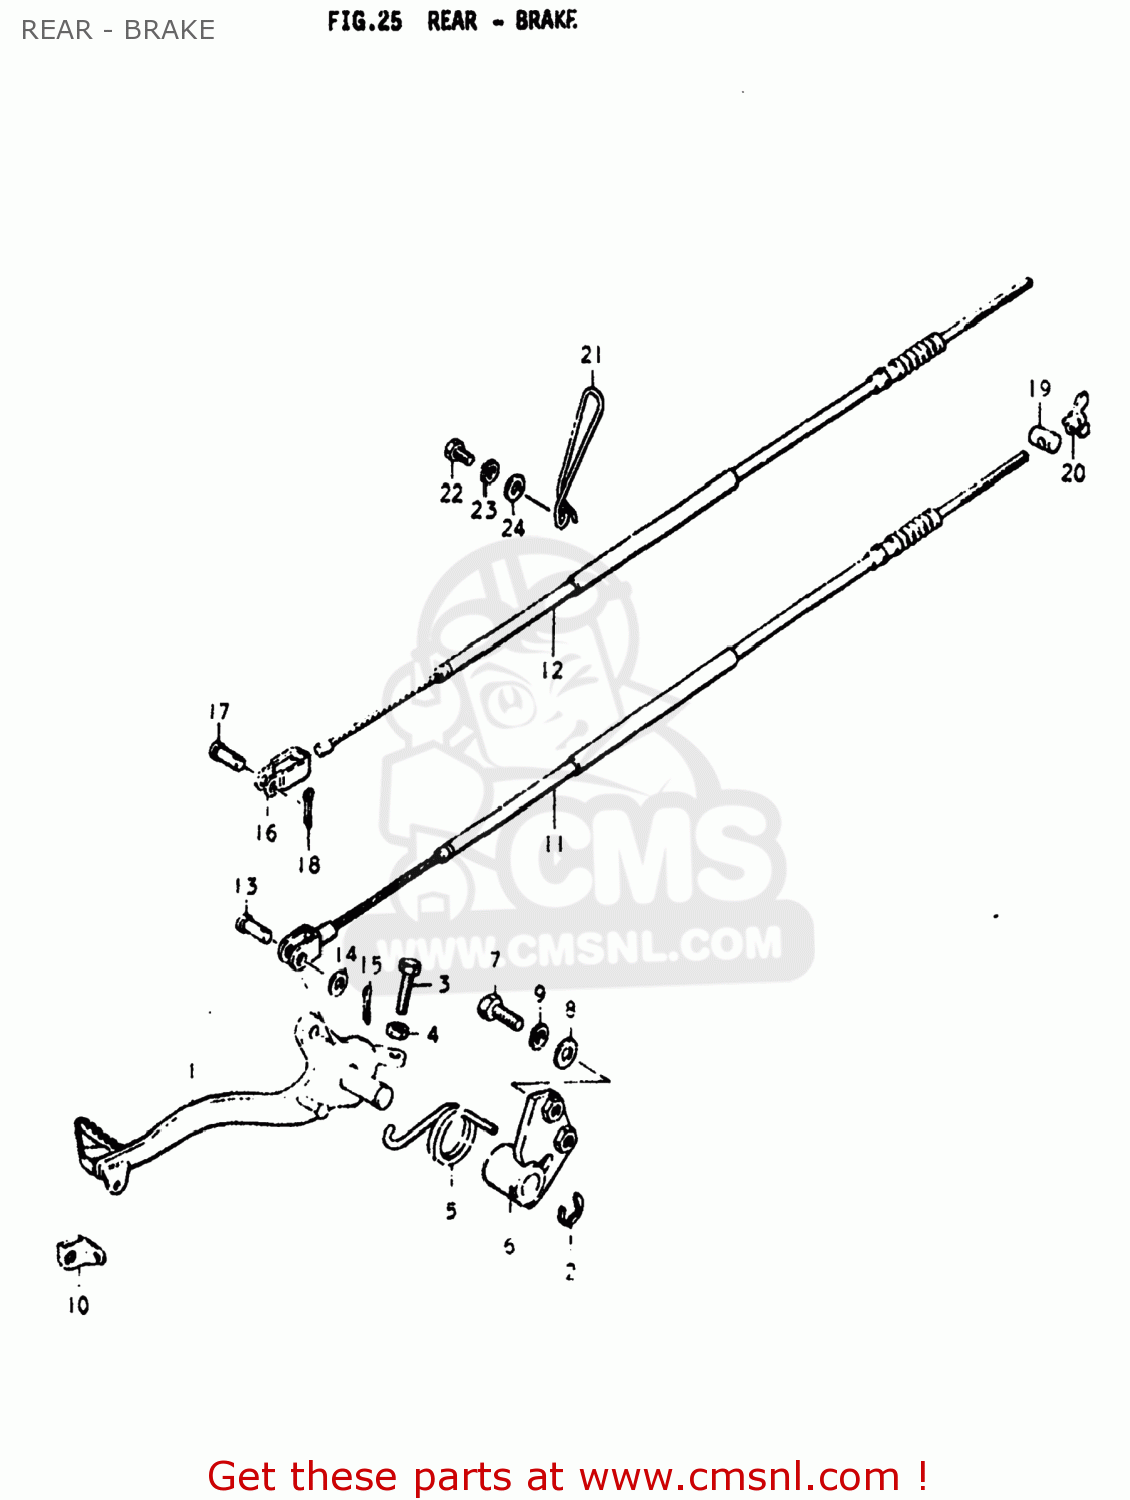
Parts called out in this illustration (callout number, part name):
1	PEDAL,BRAKE
2	E RING
3	BOLT(6X23)
4	NUT
5	SPRING
6	VALVE ASSEMBLY,WHEEL RIM
7	BOLT
8	WASHER
9	LOCK WASHER
11	CABLE ASSEMBLY,REAR BRAKE
12	CABLE ASSEMBLY,REAR BRAKE
13	PIN(L:17.5)
14	WASHER
15	PIN 20X20
16	HOOK,REAR BRAKE PEDAL
17	PIN(L:13)
18	PIN
19	PIN
20	NUT
21	GUIDE,CABLE
22	BOLT
23	LOCK WASHER
24	WASHER
